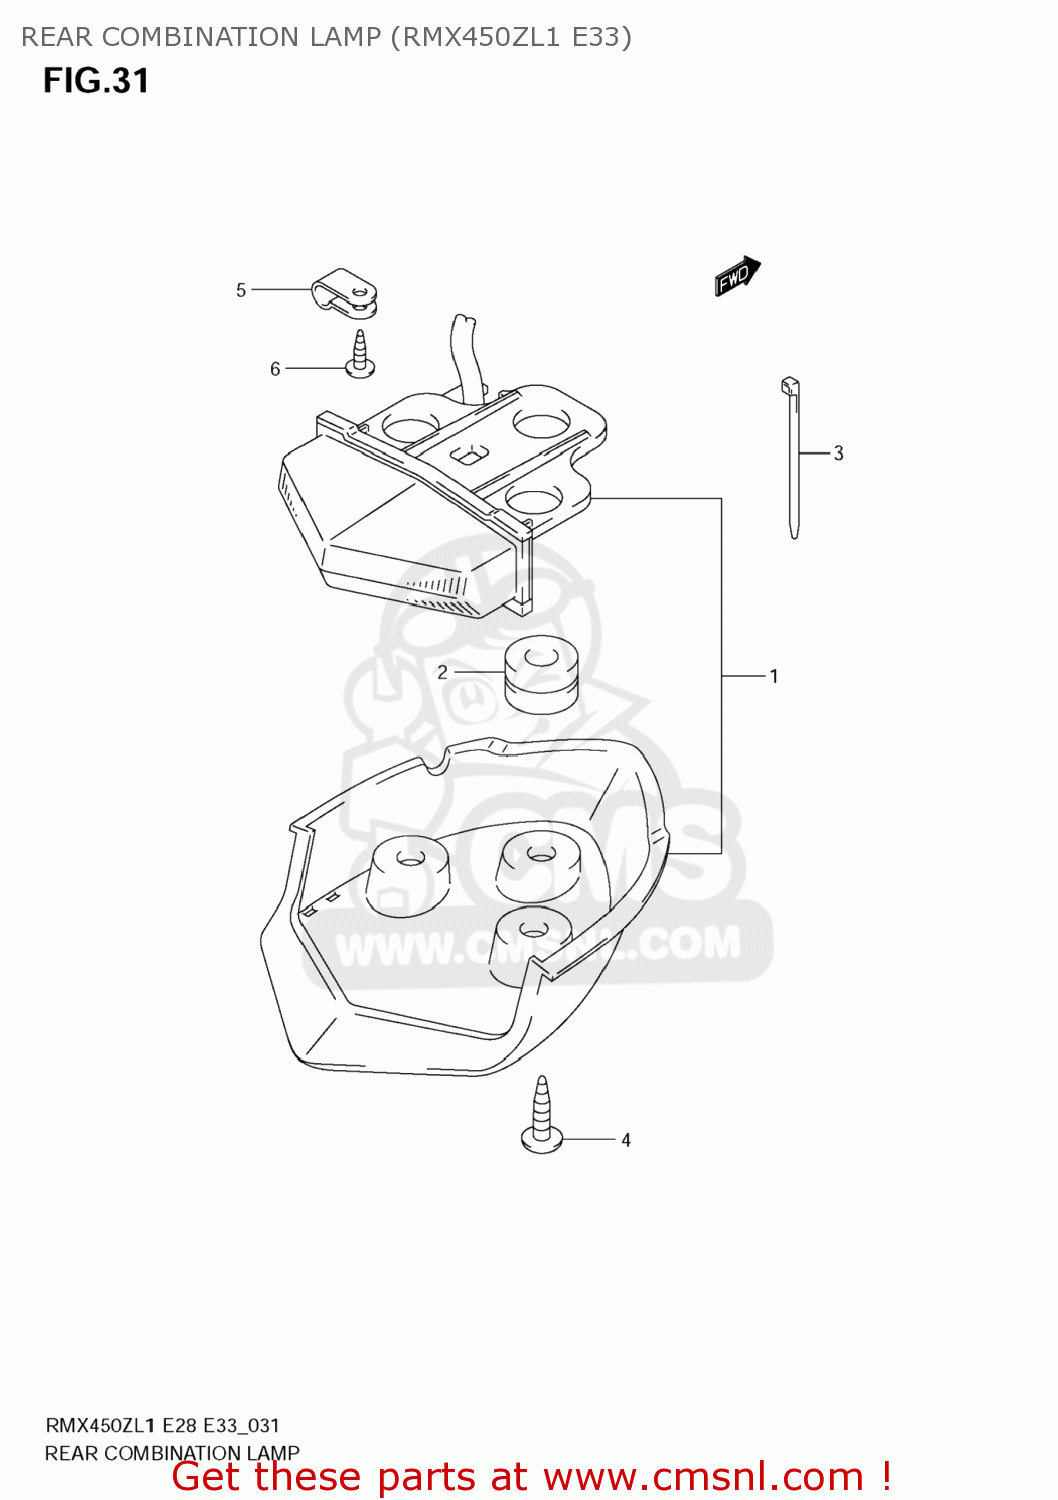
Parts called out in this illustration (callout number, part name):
1	LAMP ASSY, TAIL
2	CUSHION
3	CLAMP(L:145)
4	SCREW
5	CLAMP
6	SCREW
